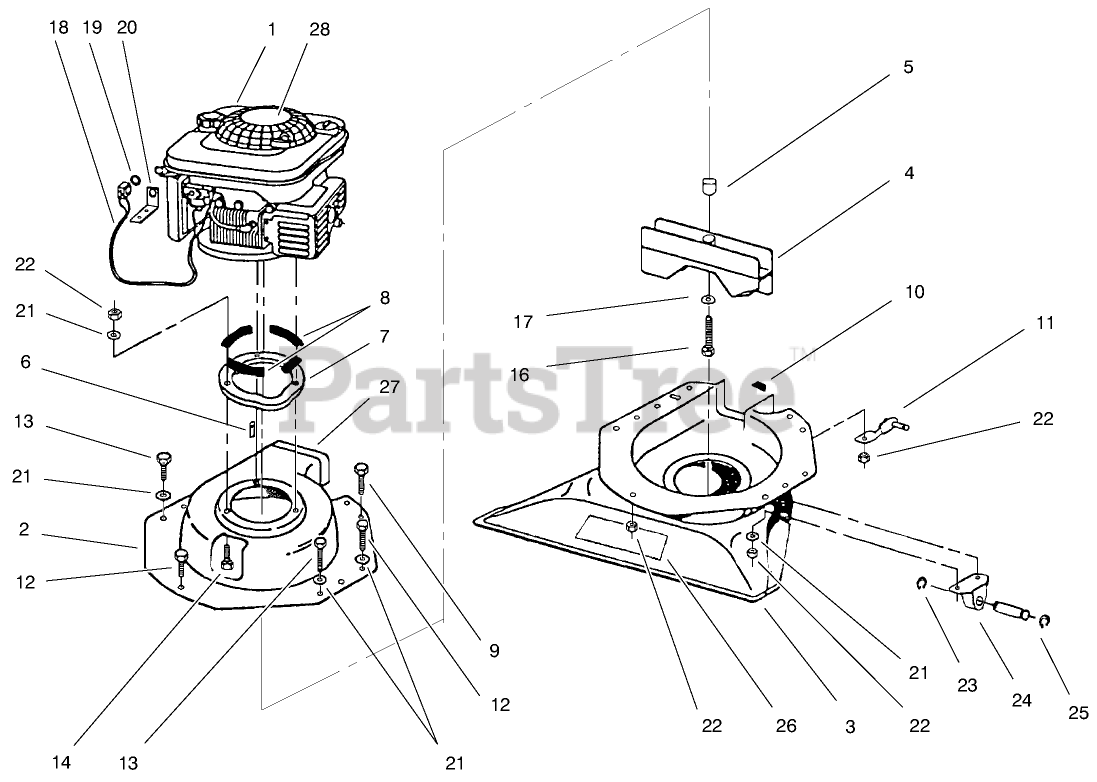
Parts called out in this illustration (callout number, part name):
2	UPPER BLOWER HOUSING
3	LOWER BLOWER HOUSING
4	ASM - COMPLETE IMPELLER
5	SPACER
7	ENGINE PLATE
8	POLYFOAM P/S BACK
9	SCREW-HH
10	RUBBER SHIM
11	WA - ADJUSTING BRACKET
12	SCREW-HH
13	SCREW-HH
14	SCREW-HH
15	SCREW-HH
16	SCREW-HH
17	WASHER-LOCK
18	SAFETY SWITCH
19	SWITCH NUT
20	SWITCH BRACKET
21	WASHER-FLAT
22	NUT-LOCK, NI
23	RETAING RING
24	HINGE
25	PIVOT PIN
26	DECAL - TORO
28	DECAL - TORO
